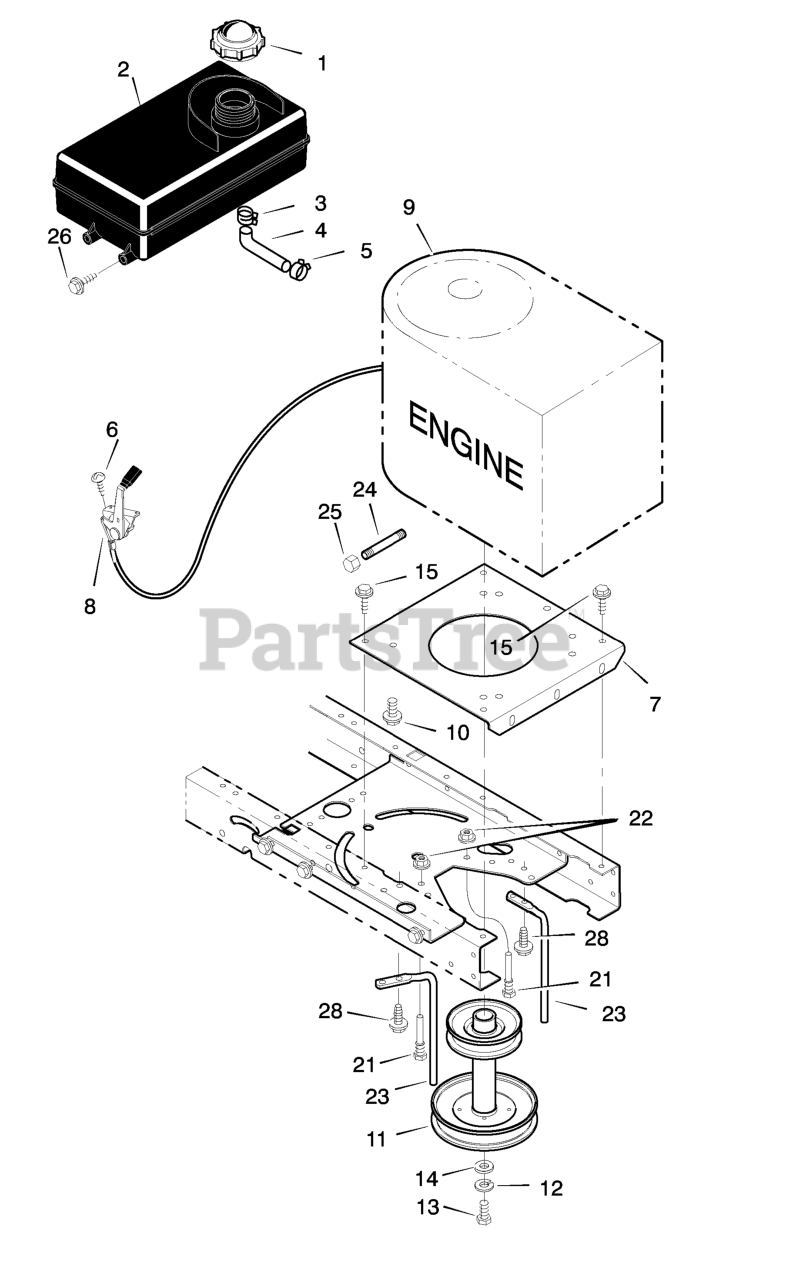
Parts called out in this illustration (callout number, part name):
1	Fuel Cap
2	Fuel Tank
3	Hose Clamp
4	Fuel Line
5	Hose Clamp
7	Plate, Engine
8	Throttle Control
9	Engine *
10	Bolt, Engine Mount
11	Stack Pulley Assembly
12	Lockwasher
13	Bolt, Hex
21	Guide, Belt
22	Nut, Flange
23	Guide, Belt
24	Pipe, Oil Drain
25	Cap, Oil Drain
28	Screw
